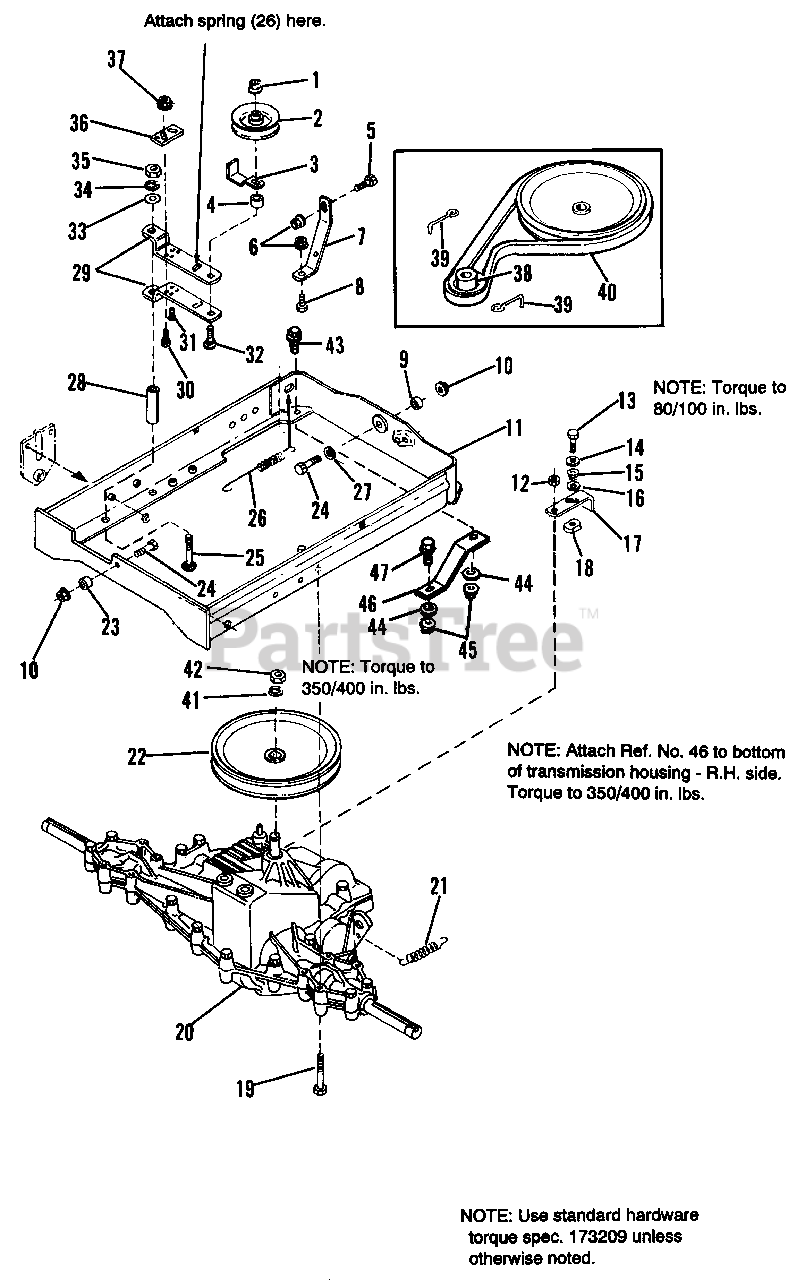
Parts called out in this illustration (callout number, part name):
1	NUT, Hex, Jam, Lock, 3/8-16
2	PULLEY, Idler
3	GUARD, Spring
4	SPACER, 25/64 x 5/8 x 11/16
5	CARRIAGE BOLT, 5/16-18 x 5/8
6	NUT, Hex, Flange Whiz, 5/16-18
7	STRAP, Torque
8	CAPSCREW, Hex, 5/16-18 x 2-1/4
9	BUSHING, Rear
10	NUT, Hex, Flange Lock, 1/2 x 13
11	CARRIER ASSY.
12	NUT, Hex, Lock, 1/4-20
13	SCREW, Tapffle, #10-24 x 1-1/4
14	WASHER, Plain, 1/4 x 1-1/4 x 5/64
16	WASHER, Plain, 13/32 x 1-1/4 x 1/16
17	LEVER, Tow Valve
19	SCREW, Taptite, 5/16-18 x 2-1/4
20	TRANSMISSION, Hydro
21	SPRING, Return
22	PULLEY, Transmission
23	BUSHING, Front
24	CAPSCREW, Hex Hd., 1/2-13 x 1-1/4
25	CARRIAGE BOLT, 5/15-18 x 2-3/4
27	WASHER, Plain, 17/32 x 1-1/4 x 5/64
28	SPACER, Pivot
29	CLEVIS, Idler Bracket
30	CAPSCREW, Hex, 1/4-20 x 3/4
31	SCREW, Taptite, 1/4-20 x 5/8
32	CARRIAGE BOLT, 3/8-16 x 2-/1/4
33	WASHER, Plain
34	LOCKWASHER, 5/16
35	NUT, Hex, 5/16-18
37	NUT, Hex, Whiz, 1/4-20
38	PULLEY, Engine
41	LOCKWASHER, 1/2
42	NUT, Hex, Jam, 1/2-20
43	SCREW, Hex, Whizlock, 5/16-18 x 3/4
44	WASHER, 5/16
45	NUT, Flange, 2-Way Lock, 5/16-18
46	STRAP, Torque
47	SCREW, Hex, Whizlock, 5/16-18 x 1-1/2
